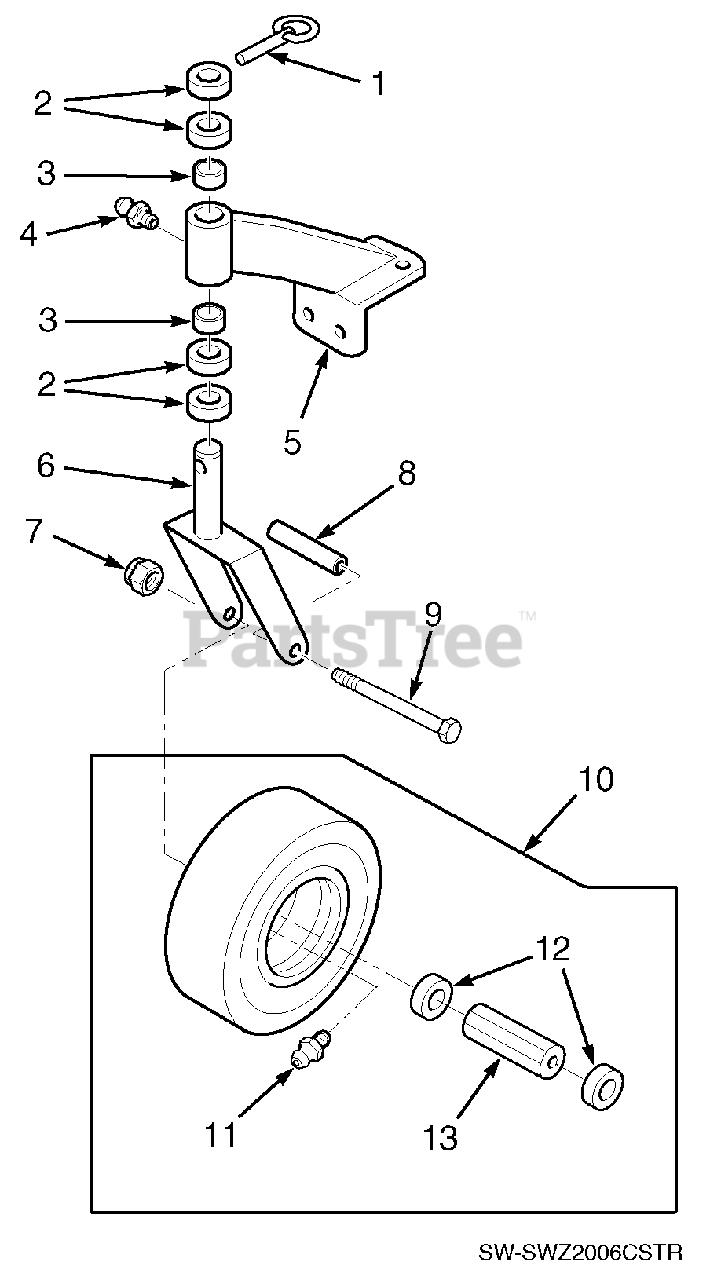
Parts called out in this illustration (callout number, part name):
1	Quick Pin
2	Spacer, Spacer Yoke, 1/2" Long
3	Bronze Bearing
4	Greasing Fitting
5	Support Assembly
6	Caster Yoke
7	Nut, Elastic Stop 1/2-13
8	Sleeve, Caster Wheel Bearing
9	Bolt, Hex Head 1/2-13 x 5-1/2"
10	Flat-Free Tire Assy.
11	Grease Fitting, 45 Degree 1/4-28
12	Retainer, Caster Wheel Bearing
13	Roller Bearing, Caster Wheel
